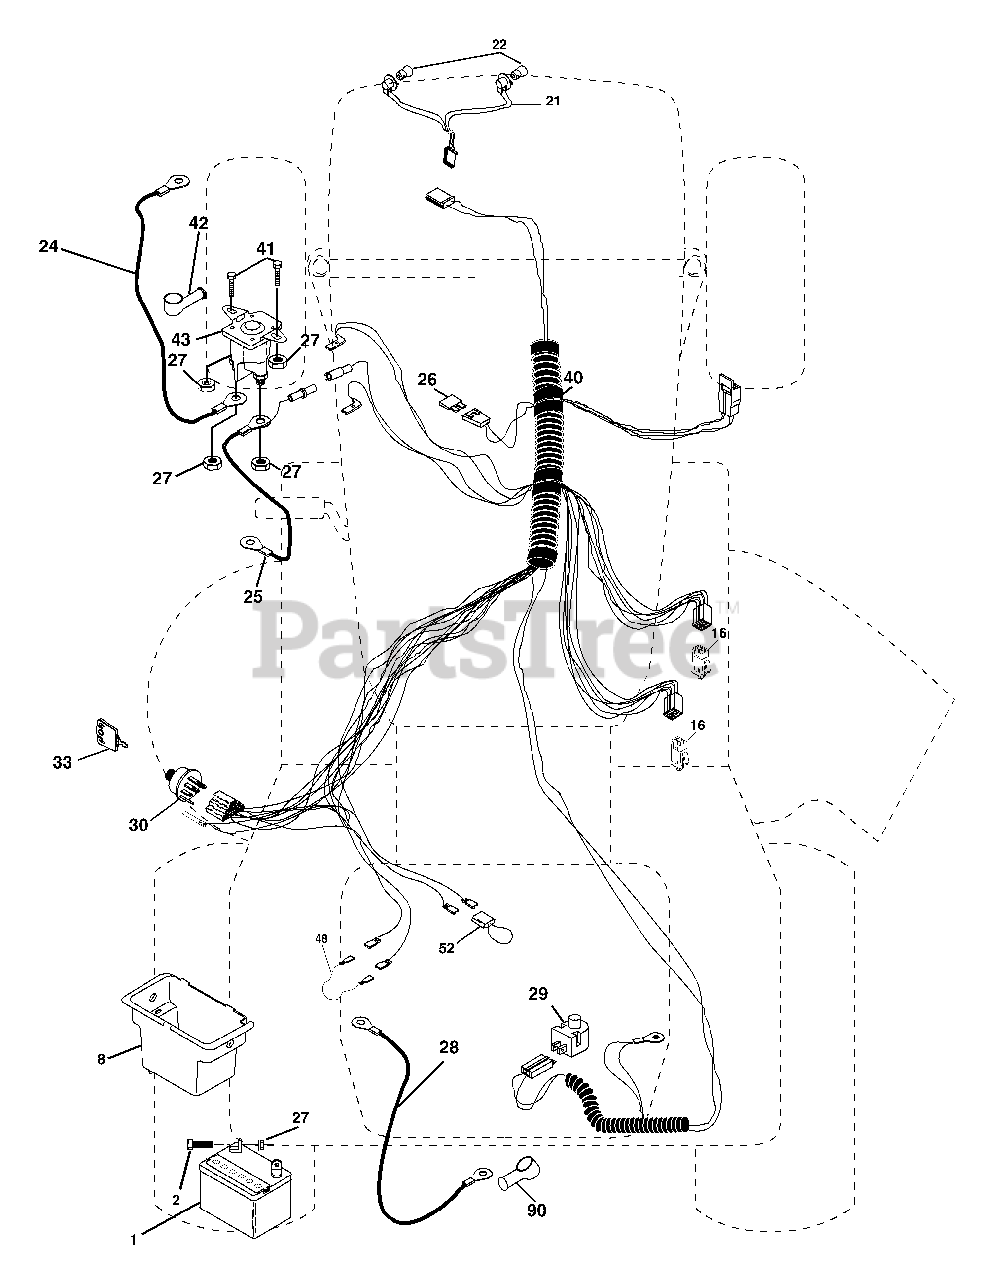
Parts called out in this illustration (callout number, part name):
1	Battery
2	Bolt Hex Hd 1/4-20 unc x 3/4
8	Box Battery
16	Switch Interlock
21	Harness Asm Light W/4152j
22	Bulb Light #1156
24	Cable Battery 6 Ga. 11"red
25	Cable Battery
26	Fuse 20 AMP
27	Nut Keps Hex 1/4-20 Unc
28	Cable Ground 6 Ga. 12"black
29	Switch Plunger Nc Gray
30	Switch Ign
33	Key Ign
40	Harness Ign
41	Bolt Blk Fin Hex 1/4-20
42	Cover Terminal Red
43	Solenoid
48	Adapter Ammeter
52	Protection Wire Loop
90	Cover Terminal Battery
